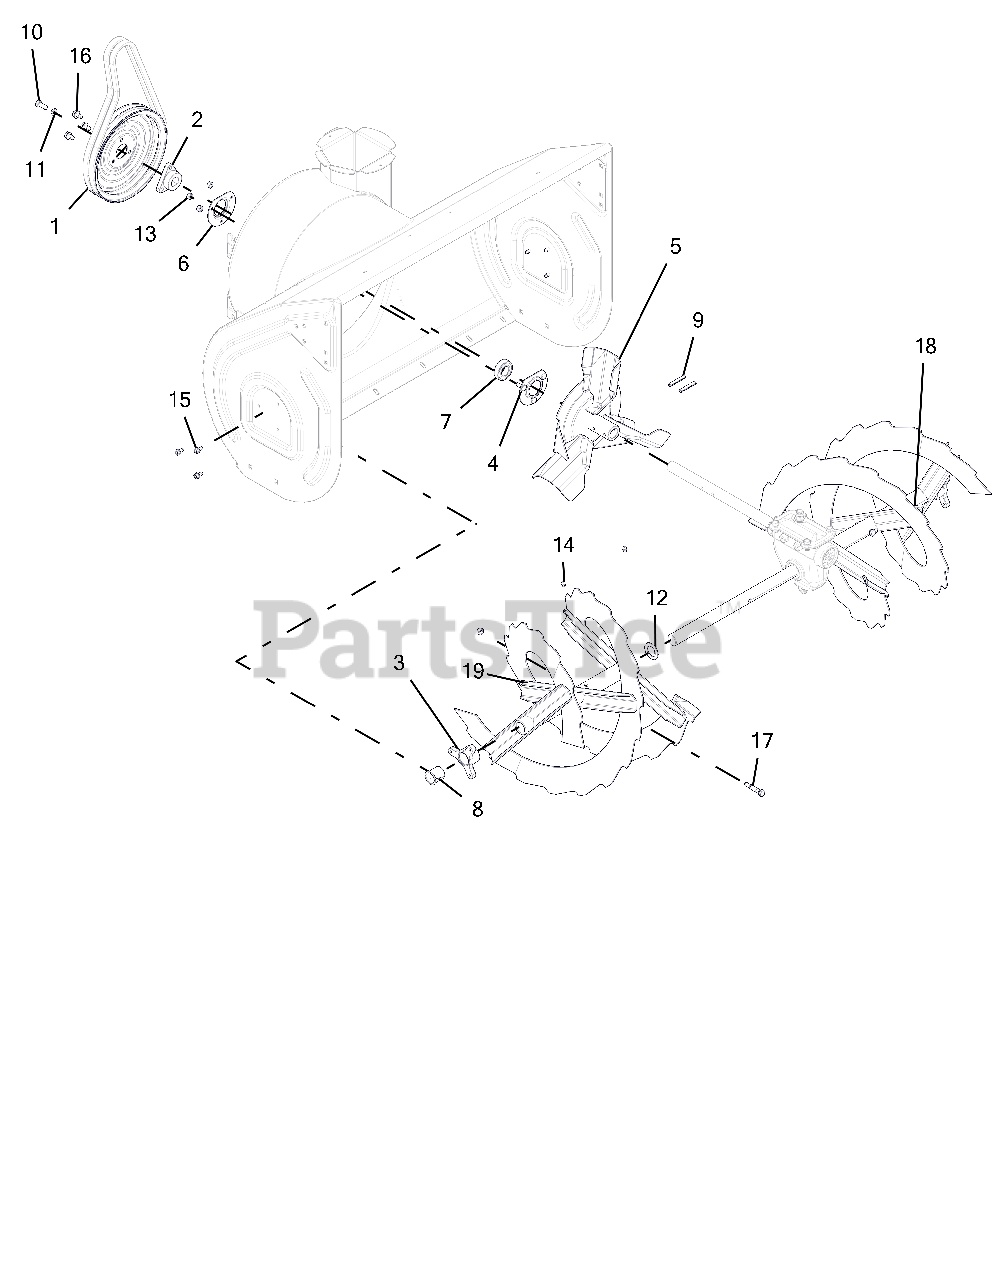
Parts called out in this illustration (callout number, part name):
1	PULLEY, SPIN FORM DUAL GROOVE
2	PULLEY HUB, D-BORE .87 PRO
3	BUSHING, RAKE SHAFT 1"
4	BEARING FLANGE
5	IMPELLER, 3 BLADE-14"
6	BEARING FLANGE
7	BRG-BALL .876X1.75X.50 RSTFP
8	BSHG-FLG SPLIT NYLINER 1.0" HP
9	PIN-ROLL .250X1.75
10	BLT-HEX .31-24X.75 YWZC GR5
11	WSHR-LK .312X.097 HVY YWZC
12	WSHR-FL-STL 1.010X1.505X.062YZ
13	@NUT-LK-CTR .25-20 YWZC
14	ZERK,FITTING .25X.125 DRIVE IN
15	SCR-TAP .25-20X.50 HWH TR YWZ
16	@SCR-TAP .31-18X.50 HWH TR YWZ
17	SHEAR BOLT SERVICE ASSEMBLY
18	RAKE, LH-32"(1 ID X 15.75 OD)
19	RAKE, RH-32"(1 ID X 15.75 OD)
